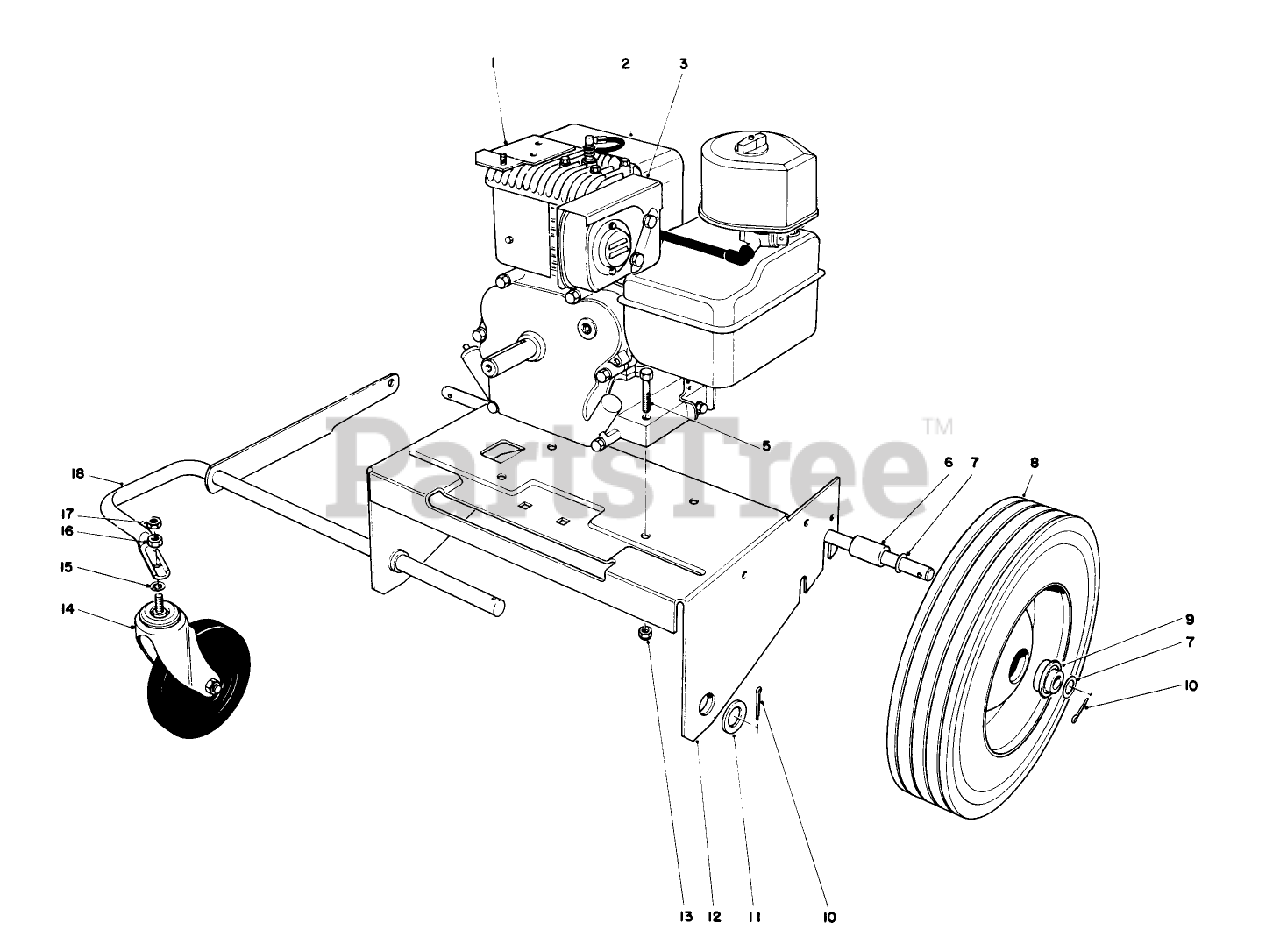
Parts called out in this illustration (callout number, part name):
1	MTG BRKT WA *B
2	Engine
3	HEAT SHIELD
5	SCREW-HH
6	SPACER-AXLE
7	WASHER
8	WHEEL
9	BEARING
10	PIN-COTTER
11	WASHER-FLAT
13	NUT-LOCK, CONE
14	CASTER
15	WASHER-LOCK/INT
16	NUT-HH
